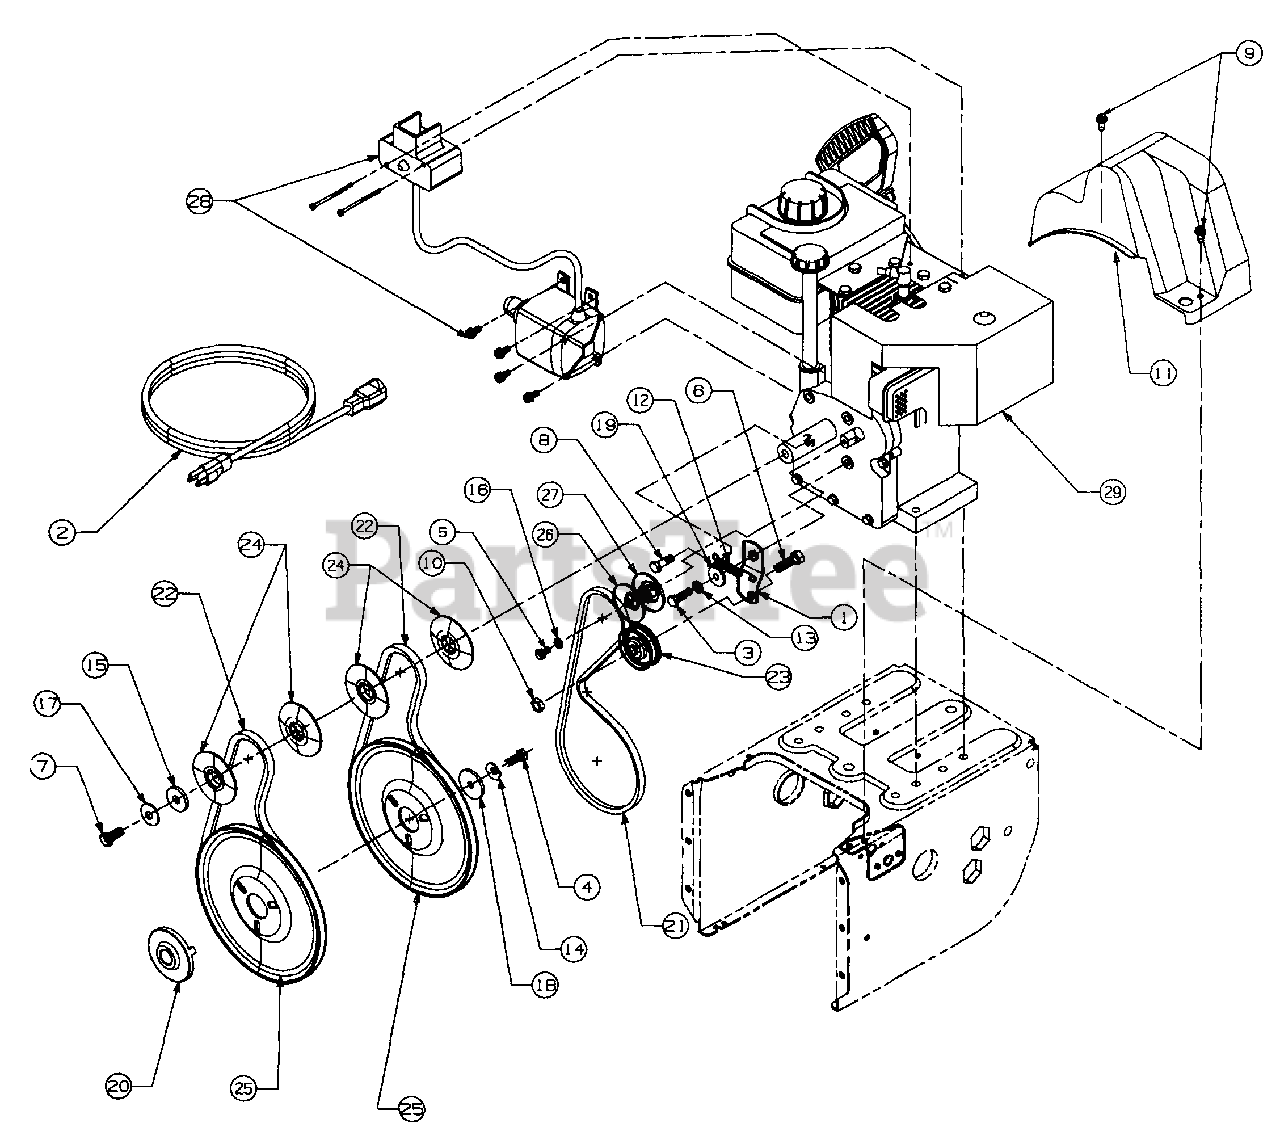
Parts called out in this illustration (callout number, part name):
3	Screw
6	Screw
11	Belt Cover
12	Spring
13	Washer - Flat
14	Washer - Bell
15	Washer - Flat
16	Washer - Lock
17	Washer - Bell
18	Washer - Flat
19	Shoulder Spacer
20	Pulley, Adapter
21	V-Belt
22	V-Belt Matched
23	Idler, Flat
24	Pulley, Half
25	Pulley - Auger
26	Pulley Half
27	Pulley Half
28	Electric Starter
29	Engine
